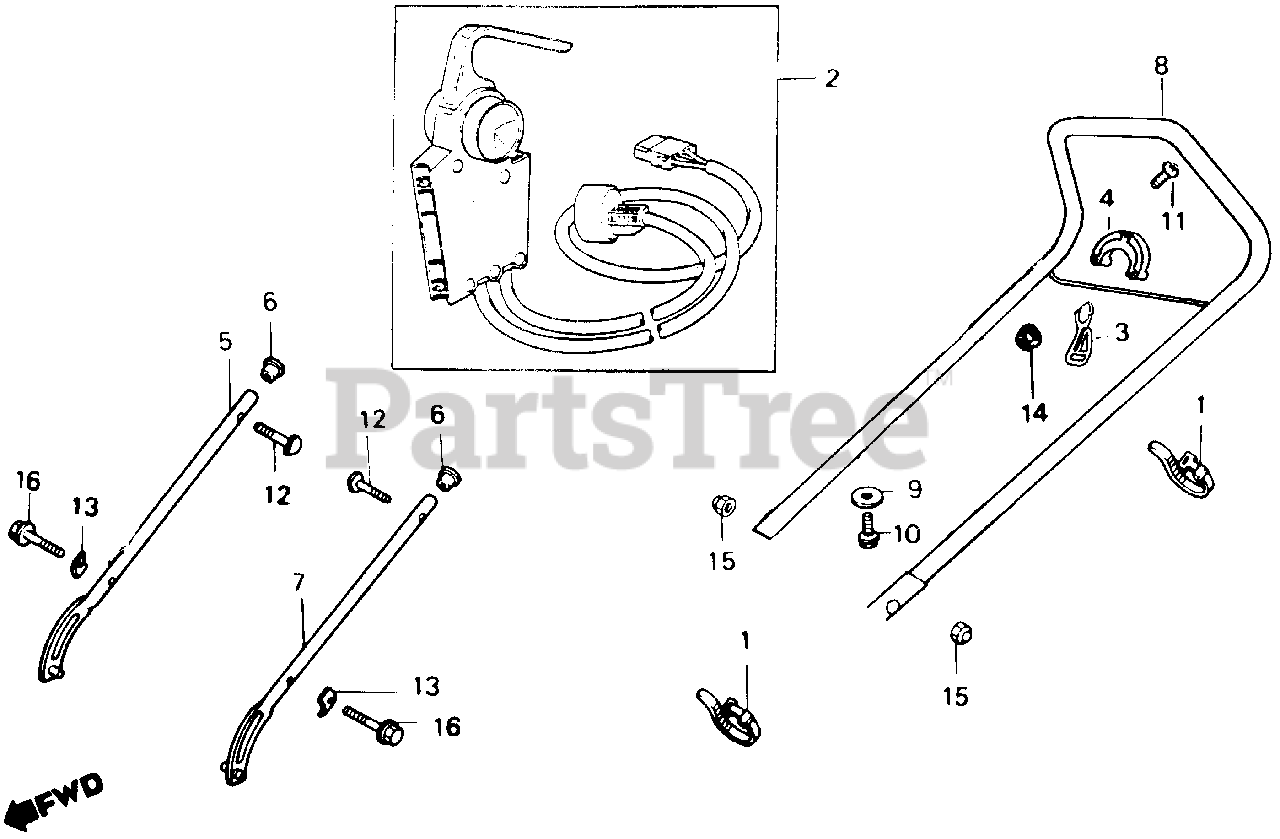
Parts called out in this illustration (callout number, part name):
1	TIE, CABLE
2	SWITCH ASSY., MOTOR (NOT AVAILABLE)
3	RELIEF, STRAIN
4	HOLDER, STRAIN RELIEF
5	PIPE, R. HANDLE (LOWER)
6	CAP, HANDLE (LOWER)
7	PIPE, L. HANDLE (LOWER)
8	PIPE, HANDLE (UPPER) *NH105* (MAT BLACK) (NOT AVAILABLE)
9	INSULATOR, HANDLE
11	SCREW, PAN (4X7)
12	BOLT, HANDLE HOLDER (NOT AVAILABLE)
13	WASHER, FRAME JOINT
14	NUT, HEX. (4MM)
15	NUT, CAP (8MM)
16	BOLT, FLANGE (8X40)
